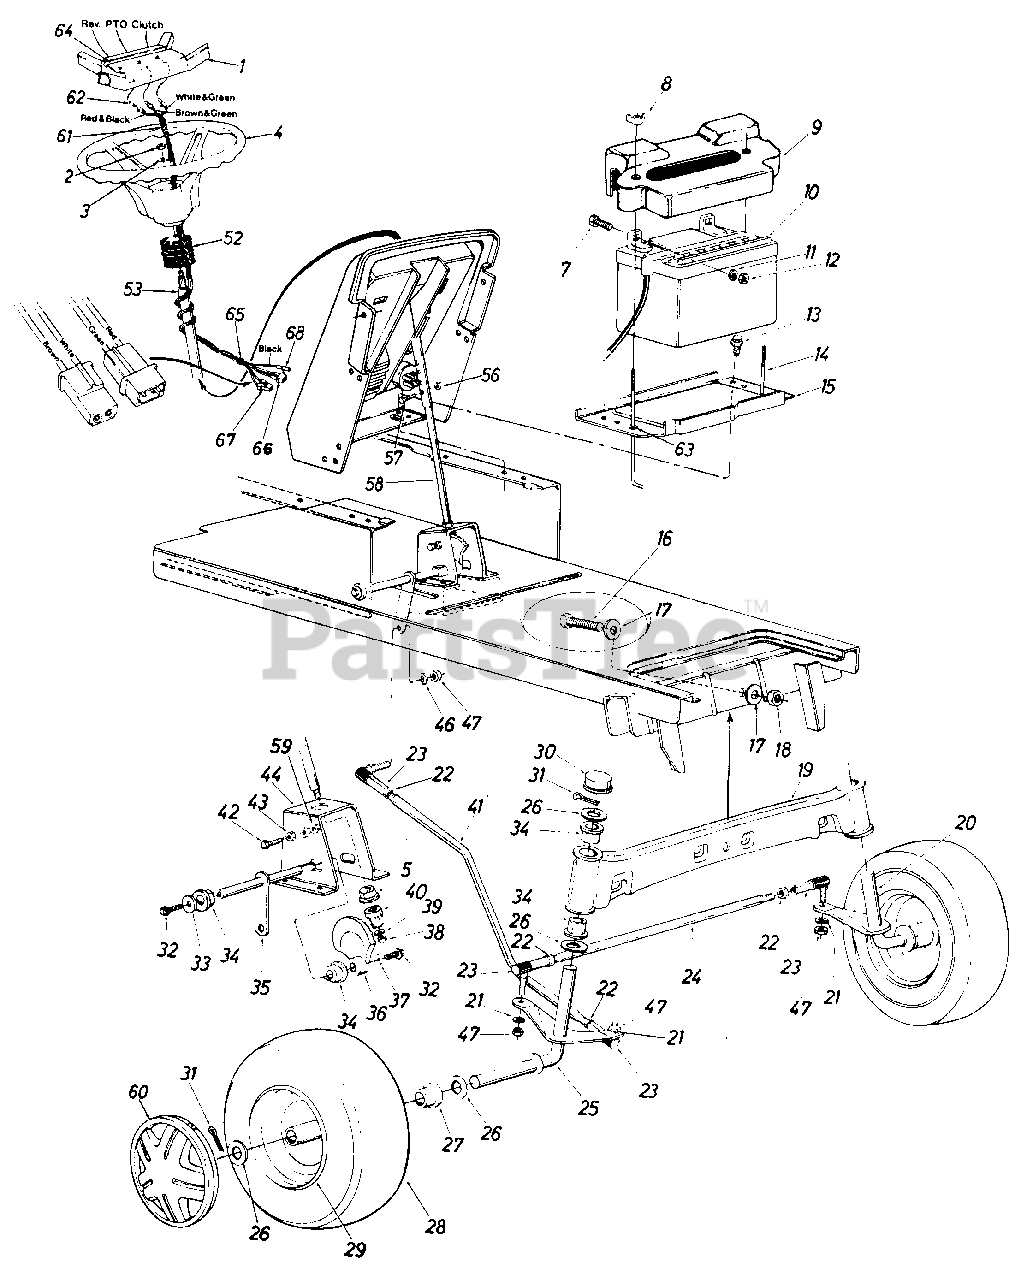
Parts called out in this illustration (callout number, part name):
1	Steering Wheel Insert
2	Hex Cent. L-Nut 5/16-24 Thd.
3	Bell-Wash. 5/16" I.D. x .87" O.D. x .060"
4	Steering Wheel
5	Plastic Hex Bearing 518" I.D.
7	Hex Bolt 1/4-20 x .62" Lg.
8	Wing Nut Plastic 1/4-20 Thd.
9	Battery Cover
10	32-V Battery
11	L-Wash. 1/4" I.D.
12	Hex Nut 1/4-20 Thd.
13	Hex Thd Rolling Scr. 1/4-20 x .50" Lg.
14	Battery Hold Down Rod
15	Battery Plate
16	Hex Bolt 5/8-18 x 2.5" Lg.
17	Flat Wash. .66" I.D. x 2.25" O.D. x .17
18	Hex Cent. L-Nut 5/8-18 Thd.
19	Front Pivot Bar Ass'y.
20	Front Axle Ass'y.-L.H.
21	L-Wash. 3/8" I.D.
22	Hex Jam Nut 3/8-24 Thd.
23	Ball Joint Ass'y.
24	Tie Rod
25	Front Axle Ass'y.-R.H.
26	Fl-Wash. .780" I.D. x 1.59" O.D.
27	Flange Bearing
28	Front Wheel Ass'y. Comp.
29	Front Wheel Rim Only
30	Dust Cover
31	Cotter Pin 5/32" Dia. x 1.00" Lg.*
32	Hex Bolt 3/8-24 x .75" Lg.(Grade 5)
33	Fl-Wash. 3/8" I.D. x 1.25" O.D. x .090"
34	Flange Double "D" Brg. .753" I.D.
35	Steering Arm Shaft Ass'y.
36	Side Gear-Steering
37	Bell-Wash. 3/8" I.D.
38	Hex Cent. L-Nut 5/16-24 Thd.
39	Fl-Wash. 5/16" I.D. x .62" O.D. x .059
40	Pinion Gear-Steering
41	Drag Link
42	Hex Cap Scr. 3/8-16 x 1.25" Lg.
43	Hex Nut 3/8-16 Thd.*
44	Steering Gear Sup. Ass'y.
46	L-Wash. 3/8" I.D.
47	Hex Nut 3/8-24 Thd.
52	Steering Bellow
53	Upper Steering Shaft
56	Hex L-Nut 1/4-20 Thd.
57	Hex Bolt 1/4-20 x 1.25" Lg.
58	Lower Steering Shaft
59	Nylon Cap
60	Hub Cap
61	Wire Harness
62	Bulb
63	Pushnut Fastener
64	Steering Wheel Insert Label
65	Clamp
66	Connector
67	Connector
68	Connector
